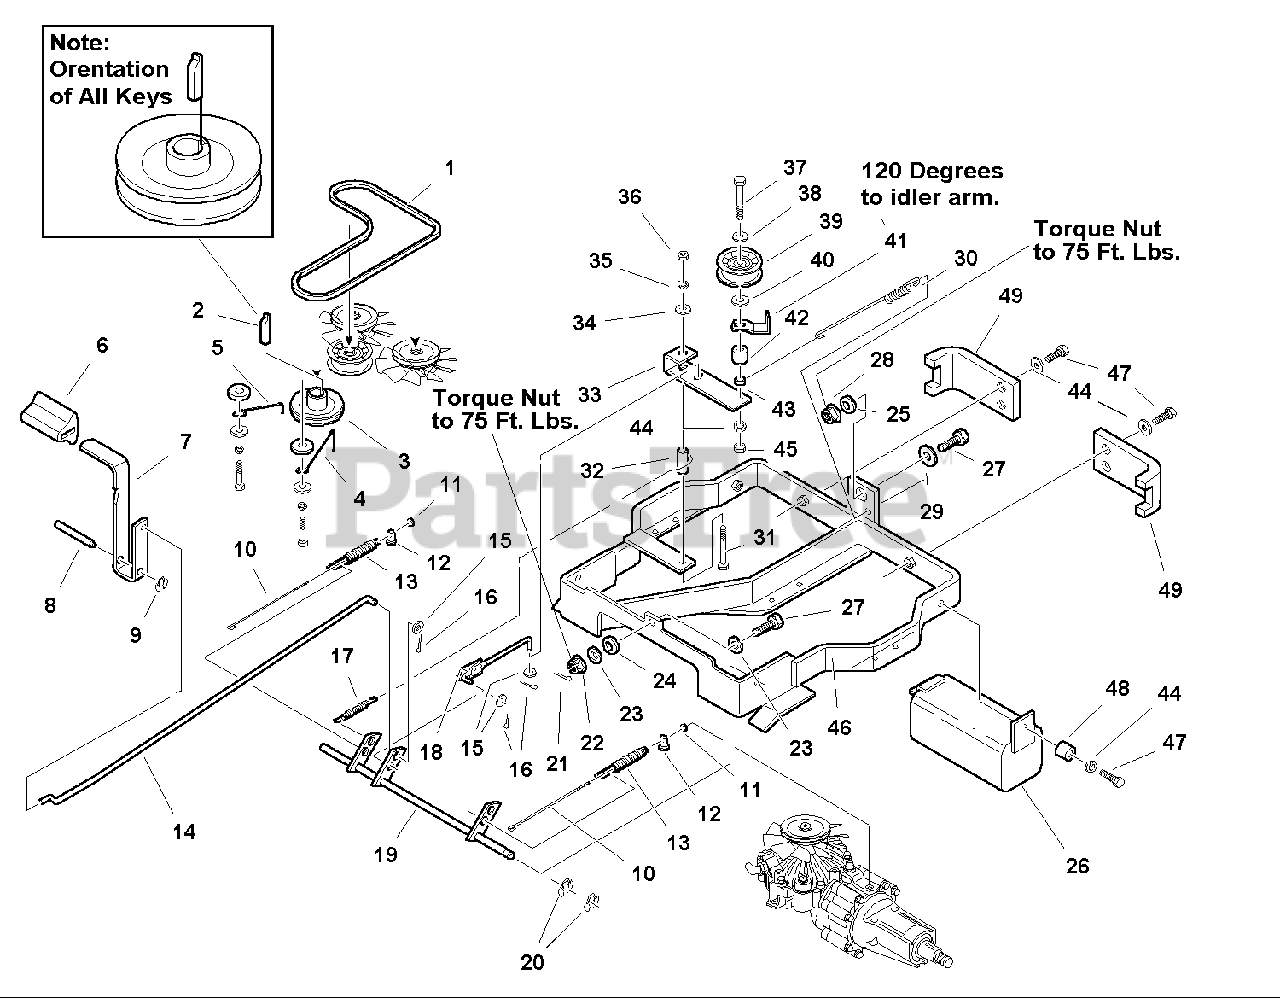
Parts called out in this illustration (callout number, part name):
1	V-BELT
3	PULLEY ASSEMBLY
4	BELT KEEPER, Engine Pulley
5	BELT KEEPER, Engine Pulley
6	PAD, Pedal
7	LEVER CLUTCH
8	PIVOT, Brake
9	RING, Klip, Ret. 3/8
11	NUT, Hex Lock ESNA 10-24
12	PIN TRUNNION
13	SPRING, Extension
14	ROD, Clutch, Front
15	WASHER, Plain 5/16
16	PIN, Cotter, 3/32 x 1
17	SPRING
18	ROD, Clutch, Rear
19	PIVOT SHAFT ASSEMBLY
20	RING, Klip, Ret., 1/2
21	PIN, Cotter, 1/8 x 1 1/2 (18 HP only)
22	NUT, Hex, Slotted, 1/2-20 (18 HP only)
22	NUT, Hex, Flange Lock, 1/2-13 (14 & 16 HP only)
23	WASHER, Spring, 1/2 (14 & 16 HP only)
26	WEIGHT ASSEMBLY
27	CAPSCREW, Hex Head, With Hole, 1/2-20 x 1-3/4 (18 HP only)
27	CAPSCREW, Hex Head, 1/2-13 x 1-1/4 (14 & 16 HP only)
28	NUT, Hex, Flange Lock, 1/2-13
29	WASHER, Plain, 1/2
31	CAPSCREW, Hex Head, 5/16-18 x 2 1/2
32	SPACER, Pivot
33	IDLER ARM ASSEMBLY
34	WASHER, Plain, 5/16
35	LOCKWASHER, Spring, 5/16
36	NUT, Hex, 5/16-18
37	CAPSCREW, Hex Head, 3/8-16 x 2 1/2
38	WASHER, Plain 3/8
39	PULLEY, Idler, Flat
40	WASHER, Plain, 3/8
41	GUARD, Spring
44	LOCKWASHER, Spring, 3/8
45	NUT, Hex, 3/8-16
46	FRAME ASSEMBLY
47	CAPSCREW, Hex Head, 3/8-16 x 2 (14 & 16 HP only)
47	CAPSCREW, Hex Head, 3/8-16 x 2 (18 HP only)
48	SPACER (18 HP only)
49	WEIGHT (18 HP only)
